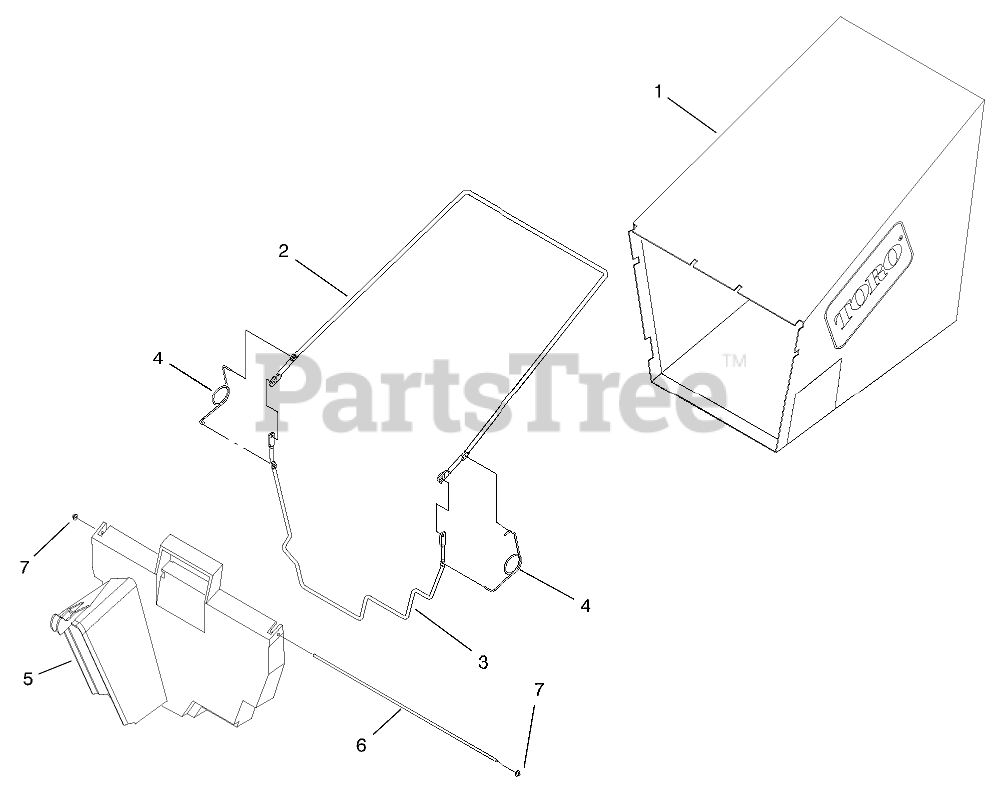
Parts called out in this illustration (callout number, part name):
1	BAG-GRASS
2	FRAME-UPPER BAG
3	FRAME-LOWER BAG
4	SPRING
5	DOOR-BAG
6	Hinge
7	NUT-PUSH
